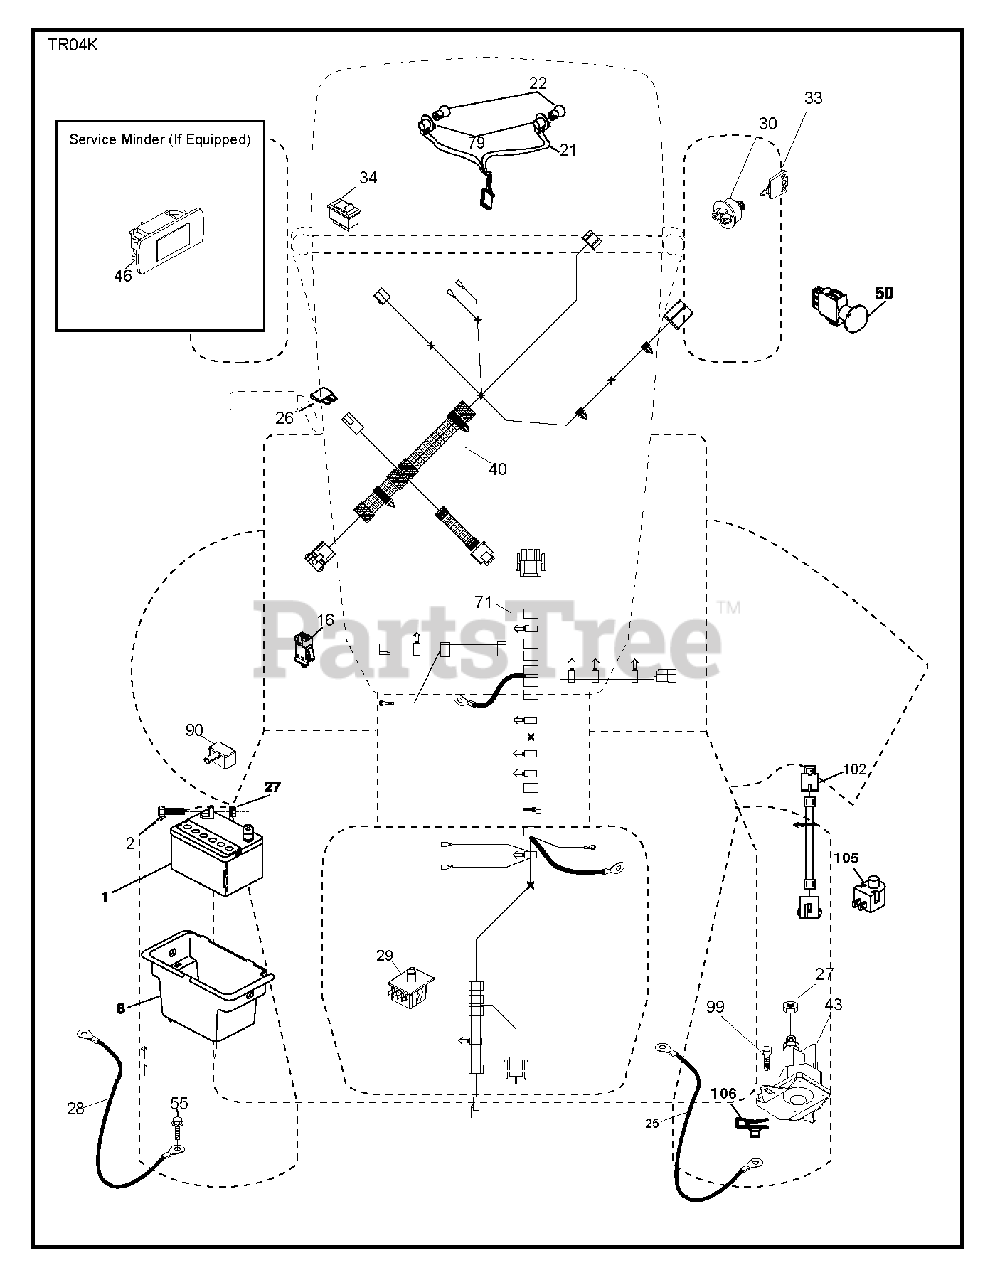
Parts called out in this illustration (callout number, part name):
2	BOLT.HEX.1/4.X.3/4.DICHROMATE
8	BOX.BATTERY.MNT.REAR.L
16	SWITCH INTERLOOK PUSH-IN
21	HARNESS.LIGHT W/4152J BULBS
22	LIGHTBULB
25	CABLE.BATT.RED.8GA.17
26	FUSE 20AMP
27	NUT
28	CABLE.GROUND.REAR.BATTERY.8G
29	SWITCH.SEAT.DP W/RAMPS
30	SWITCH.IGN.DELTA.W.LGH.ROS
33	KEY.CHAIN.BLISTER.PACK.GEN.USA
34	SWITCH LT
40	HARNESS.TEX.DASH.ELEC.REAR BAT
43	SOLENOID.W/BRASS.PLUNGER
46	Hour Meter Gauge
50	PTO SWITCH
55	SCREW 5/16"
71	HARNESS.TEX.CHSSIS.REAR.BATT
79	BULB HOLDER ASM.
90	COVER.TERMINAL.BATTERY
99	SCREW HEXWSHR 1/4-20X3/4
102	HARNESS.PIGTAIL.VARIATOR.SD
105	REVERSE SWITCH
106	1/4-20 U NUT
